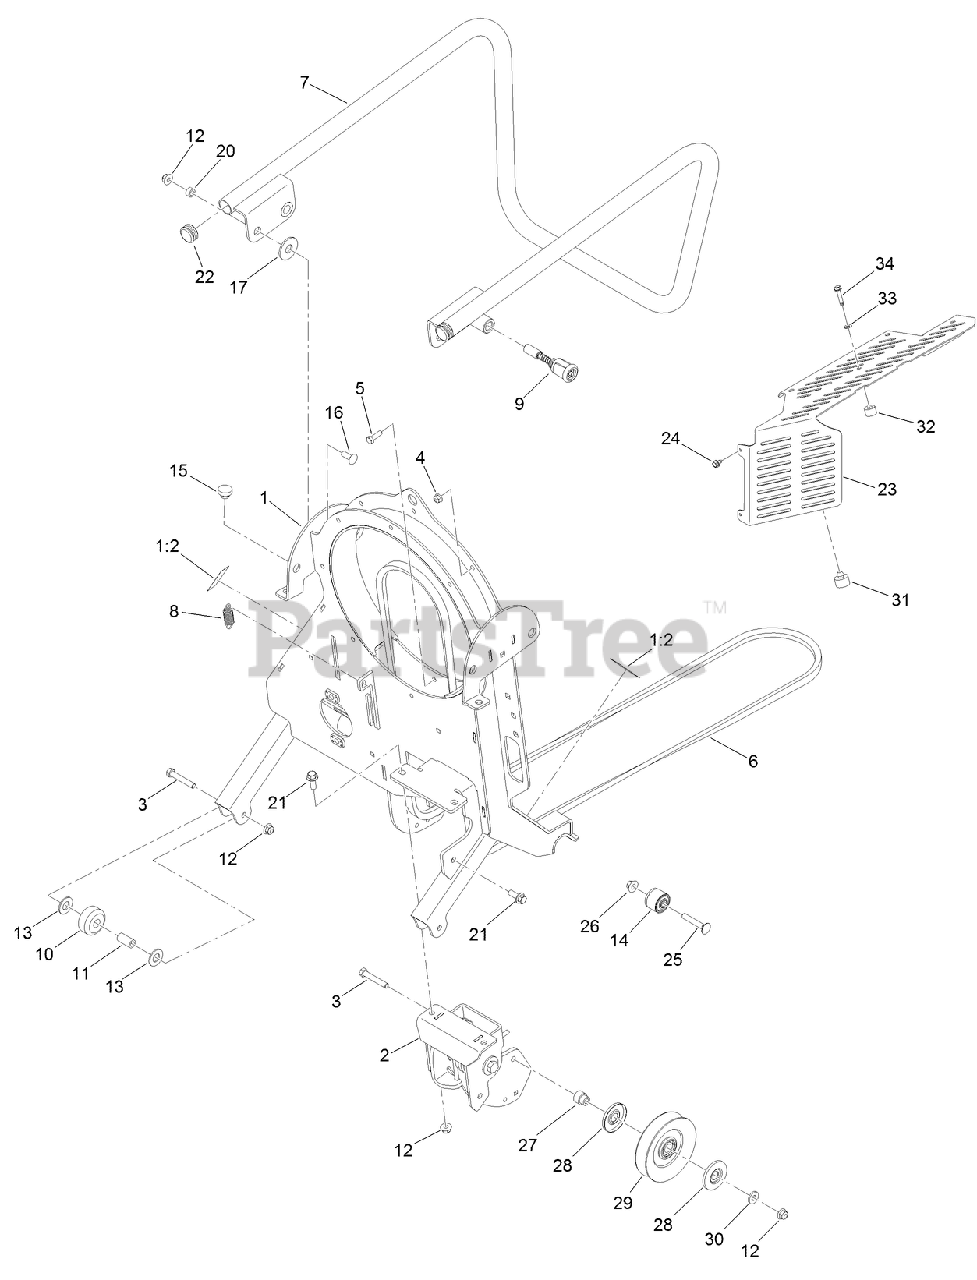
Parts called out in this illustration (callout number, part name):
1	BLOWER FRAME SERVICE ASM
1:2	DECAL-DANGER
2	IDLER TORSION ASM
3	SCREW-HH
4	NUT-HF, NI
5	SCREW-HH
6	BELT-V
7	BLOWER KICKSTAND ASM
8	SPRING-BRAKE
9	PIN-SPRING
10	ROLLER
11	SPACER
12	NUT-HF, NI
13	WASHER-FLAT
14	PIVOT-MOUNT ASM
15	BUMPER-RUBBER
16	SCREW-CARR
17	SPACER
20	SPACER
21	SCREW-HHF
22	CAP-TUBE
23	LEAF GUARD KIT
24	SCREW-HWHTF
25	SCREW-HH
26	NUT-HF
27	BUSHING-IDLER
28	SHIELD-GUARD, DUST
29	PULLEY-IDLER
30	WASHER-SPACER
31	BUMPER-GROMMET
32	SPACER-NYLON
33	WASHER-NYLON
34	SCREW-HWH THD CUT
